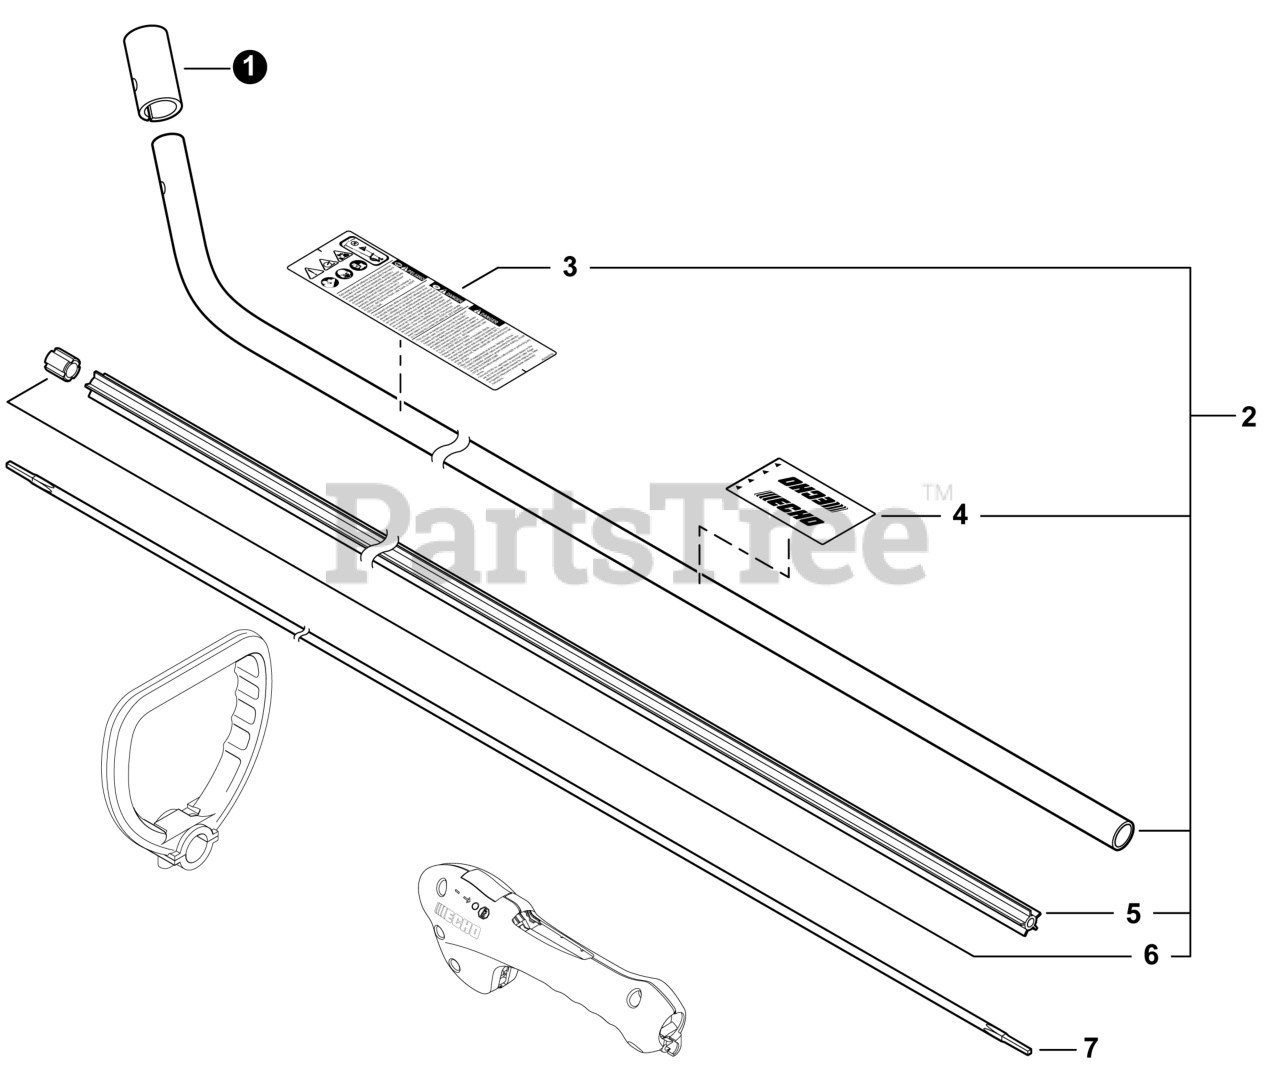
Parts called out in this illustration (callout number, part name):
2	MAIN PIPE ASSY
3	LABEL - CAUTION
4	LABEL - HANDLE LOCATION
5	LINER - FLEXIBLE
7	DRIVESHAFT - FLEXIBLE
